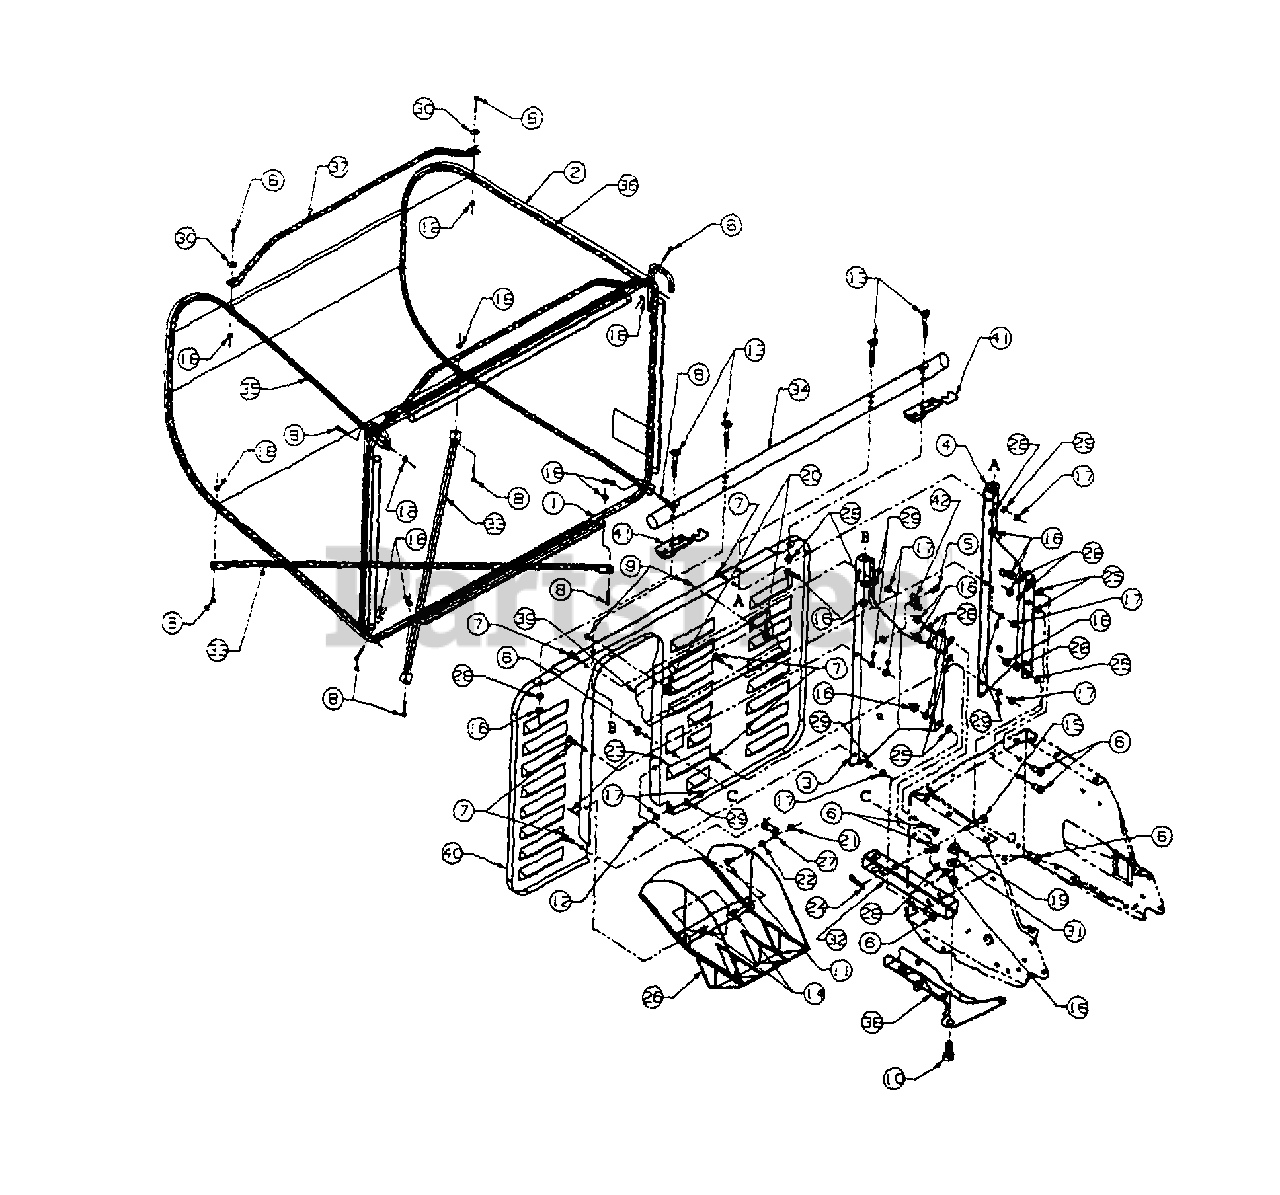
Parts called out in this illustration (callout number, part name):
3	Grass Catcher Support-R.H.
4	Grass Catcher Support-L.H.
5	Hex Washer Hd. AB-Tap Scr. 1/4-20 x .5"
6	Hex Bolt 5/16-18 x .75" Lg.
7	Hex Bolt 1/4-20 x .625" Lg.
8	Hex Bolt #10-24 x .88" Lg.
9	Truss Mach. B-Tap Scr. #10 x .5"
10	Hex Bolt 1/2-13 x 1" Lg.
11	Carriage Bolt 1/4-20 x .62" Lg.
12	Hex Bolt 1/4-20 x 1" Lg.
13	Curved Carr. Bolt 5/16-18 x 2"
14	Clevis Pin .25" Dia.
15	Clevis Pin 3/8" Dia.
16	Hex Nut 5/16-18 Thd.
17	Hex Nut 1/4-20 Thd.
18	Hex Sems Nut #10-24 Thd.
19	Hex Nut 1/2-13 Thd.
20	Speed Clip Nut #10-24 Thd.
21	Hex L-Nut 1/4-20 Thd.
22	Hex Sems Nut 1/4-20 Thd.
23	Cotter Pin 3/32" Dia.
24	Hairpin Clip
25	Speed Nut 5/16-18 Thd.
26	Rear Discharge Chute
27	Ext. Spring 2.1" Lg.
28	Lock Washer 5/16" I.D.
29	Lock Washer 1/4" I.D.
30	Flat Washer .194" I.D. x .62" O.D.
31	Bell-Washer .5" I.D. x 1" O.D.
